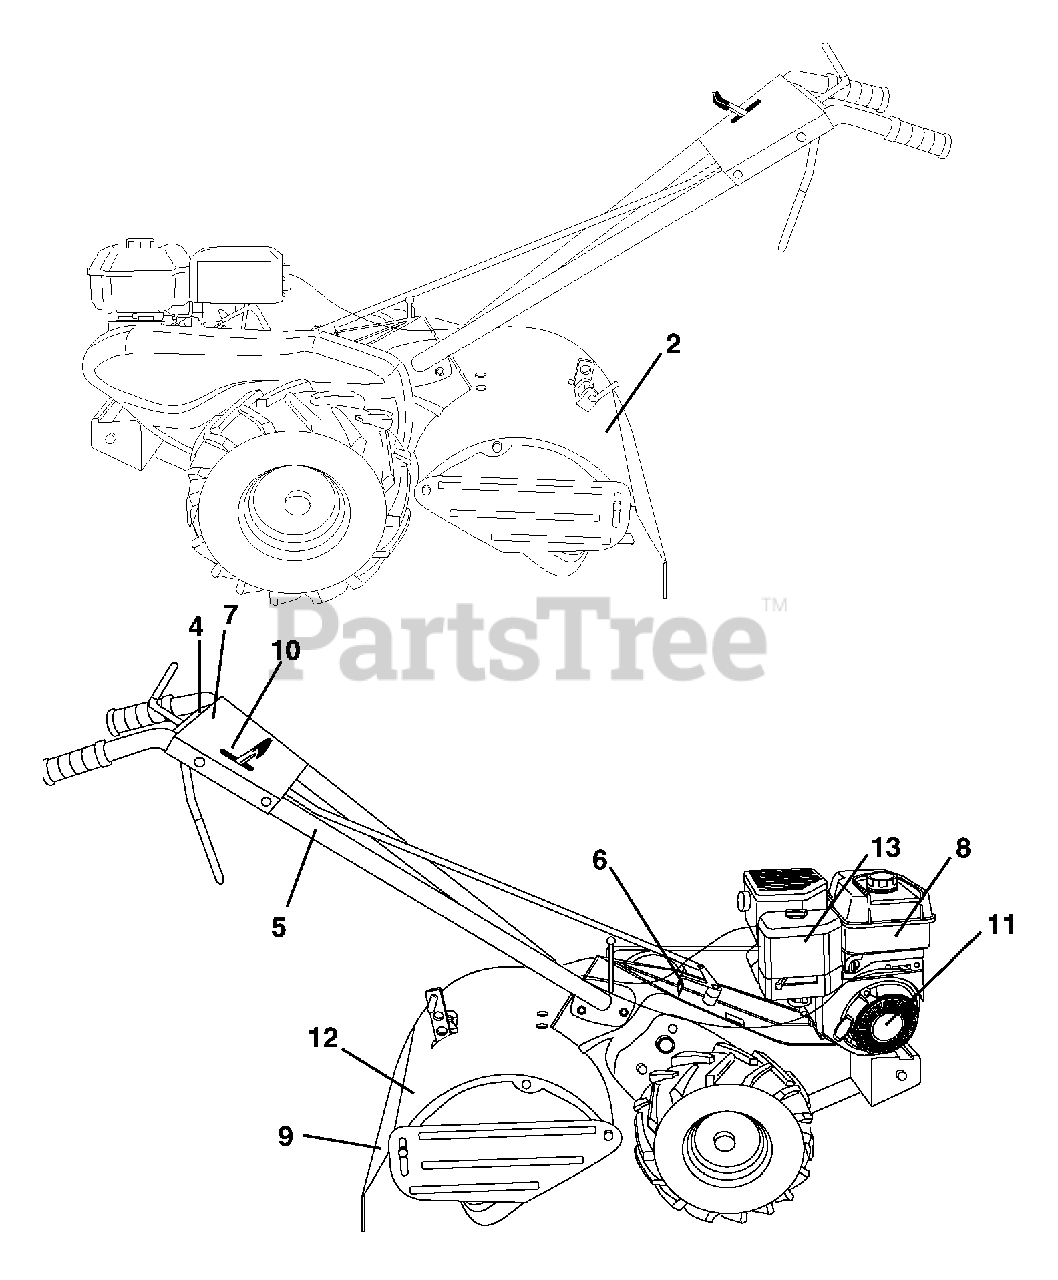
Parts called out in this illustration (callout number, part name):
2	Decal, Logo
4	Decal, Instruction, Tilling
5	Decal, Hand Placement
6	Decal, Shift Indicator
7	Decal, Pnl Cntrl Reverse
8	Decal, OHV.N-I/C
9	Decal, Warning, Rotating Tines
10	Decal, Throttle
11	Decal, Rewind Intek
12	Decal, Warning Till
13	Decal, B&S Tiller
